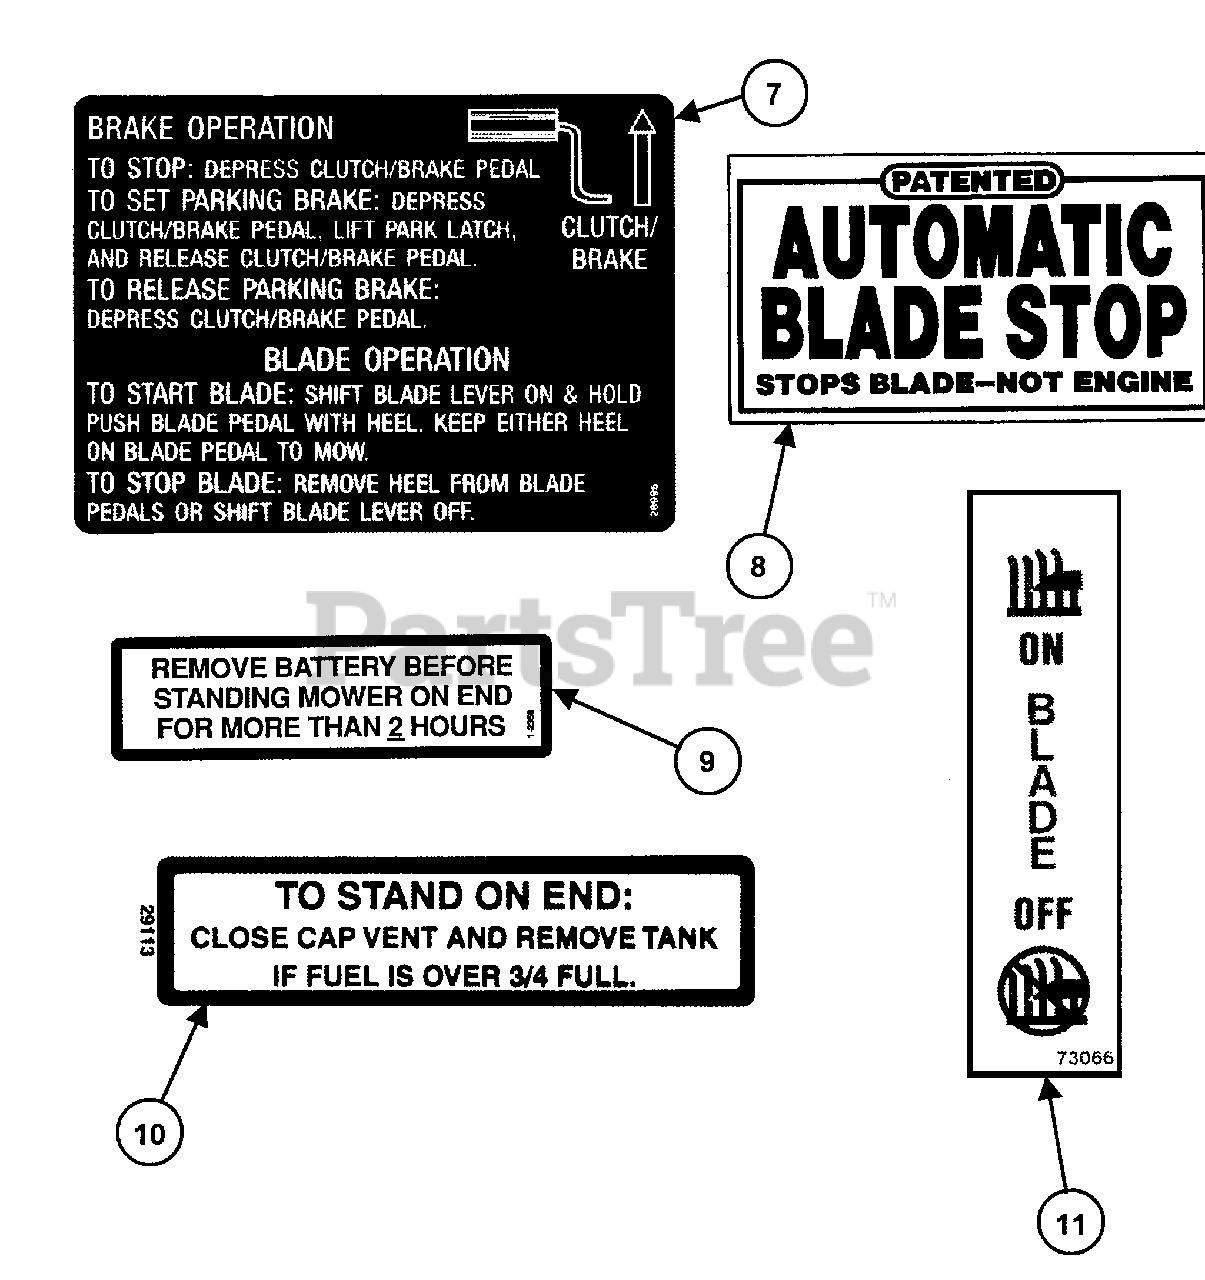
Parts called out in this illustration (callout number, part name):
7	DECAL, Brake/Blade Operation
8	DECAL, Automatic Blade Stop
9	DECAL, Battery Storage
10	DECAL, Caution, Fuel
11	DECAL, Blade Engagement (42")
